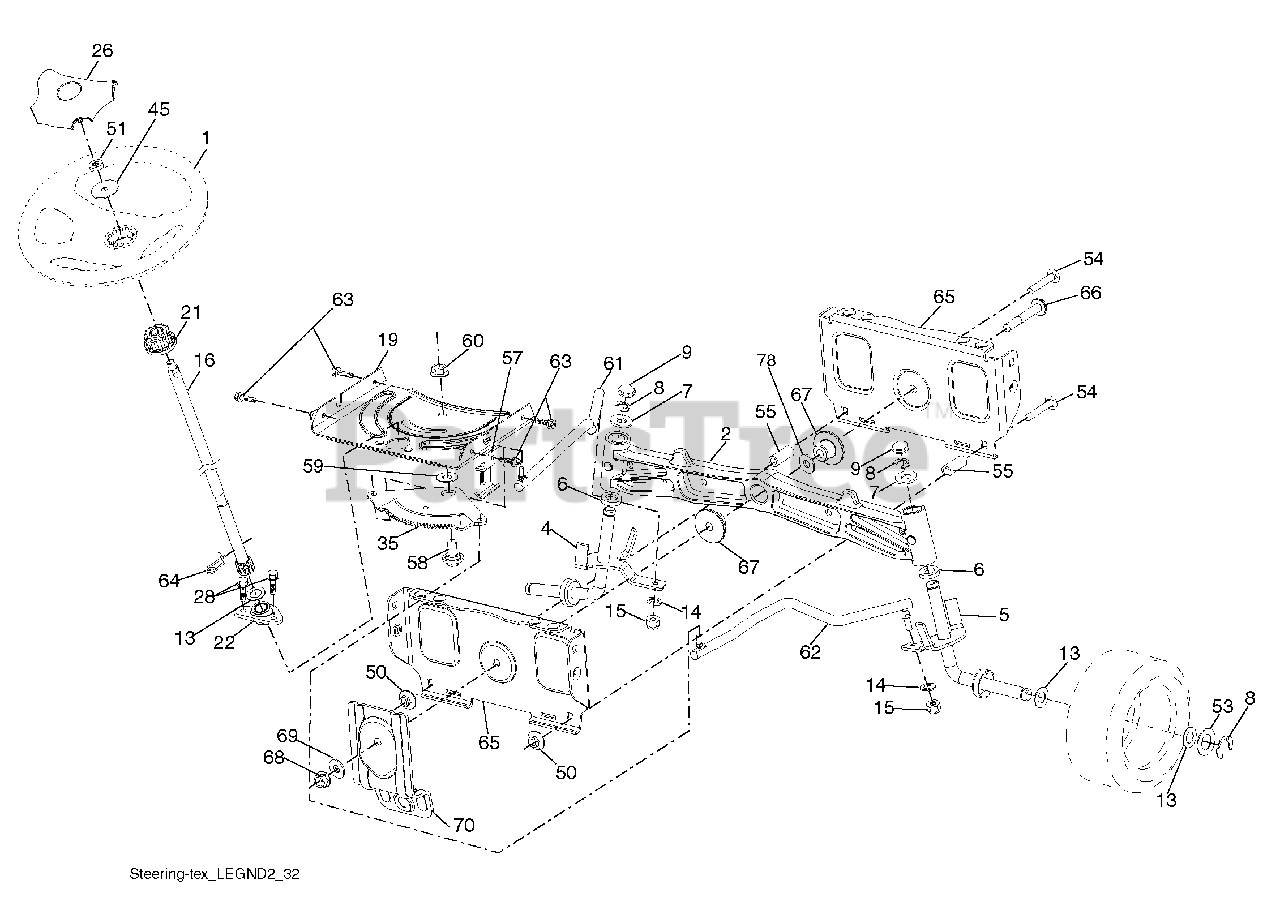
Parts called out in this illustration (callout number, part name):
1	Wheel, Steering
2	Axle Asm., Front
4	Spindle Asm., LH
5	Spindle Asm., RH
6	Bearing, Race Thrust Harden
7	Washer 25/32 x 1-5/8 x 16 Ga.
8	Ring, Klip #T5304-75
9	Cap, Spindle
13	Washer 25/32 x 1-1/4 x 16 Ga.
14	Washer, Lock Hvy Hlcl Spr 3/8
15	Nut, Crown Lock 3/8-24 unf
16	Shaft Steering
19	Plate Steering
21	Adapter, Wheel Steering
22	Steering Support Lower
26	Insert, Wheel Steering
28	Screw 3/8-16 x 3/4
35	Gear, Sector Plate
45	Washer 9/16 ID x 2-3/8 OD 12 Ga.
50	Nut Lock Flg. 3/8-16
51	Nut Hex Jam Toplock 1/2-20 unf
53	Washer Hardened .793 x 1.637 x .060
54	Bolt Hex 3/8-16 x 2-1/4
55	Spacer Axle Brace
57	Bracket Upstop
58	Bolt Shoulder Sector Pivot CFM
59	Washer Thrust Sector Steering
60	Nut Flange Lock 5/8-11
61	Draglink LH
62	Draglink, RH
63	Screw 5/16-18 x 3/4
64	Retainer Clip Spring Steering
65	Brace Axle Front
66	Bolt Hex Fghd 7/16-14 x 3 Serr
67	Bushing Front Axle
68	Nut Lock Flange 7/16-14 Gr. 5
69	Washer 1.5 x .505 x .118
70	Bracket Deck Susp. Front
78	Washer Thrust .515 x .750 x .033
